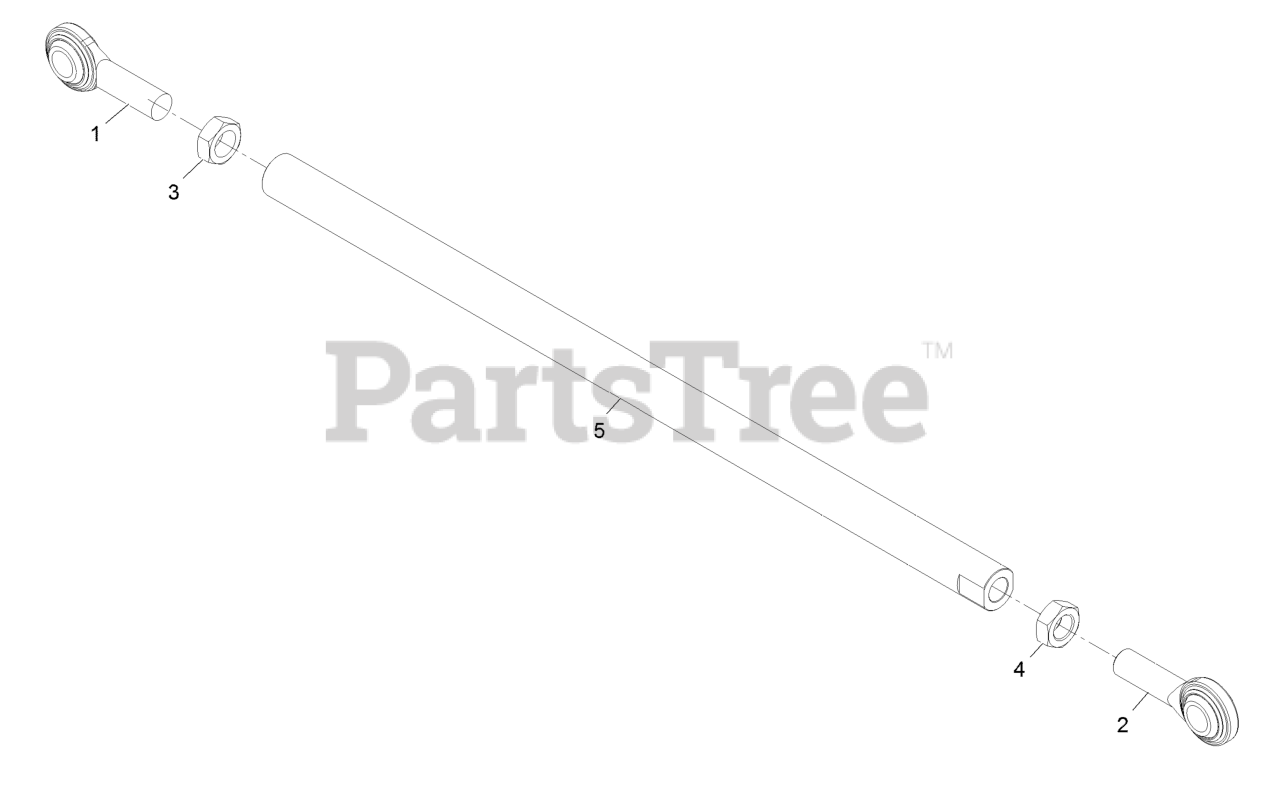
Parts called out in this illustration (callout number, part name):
1	BALLJOINT-SPHERICAL
2	BALLJOINT-SPHERICAL
3	NUT-JAM
4	NUT-JAM
5	LINK-HEIGHT OF CUT
